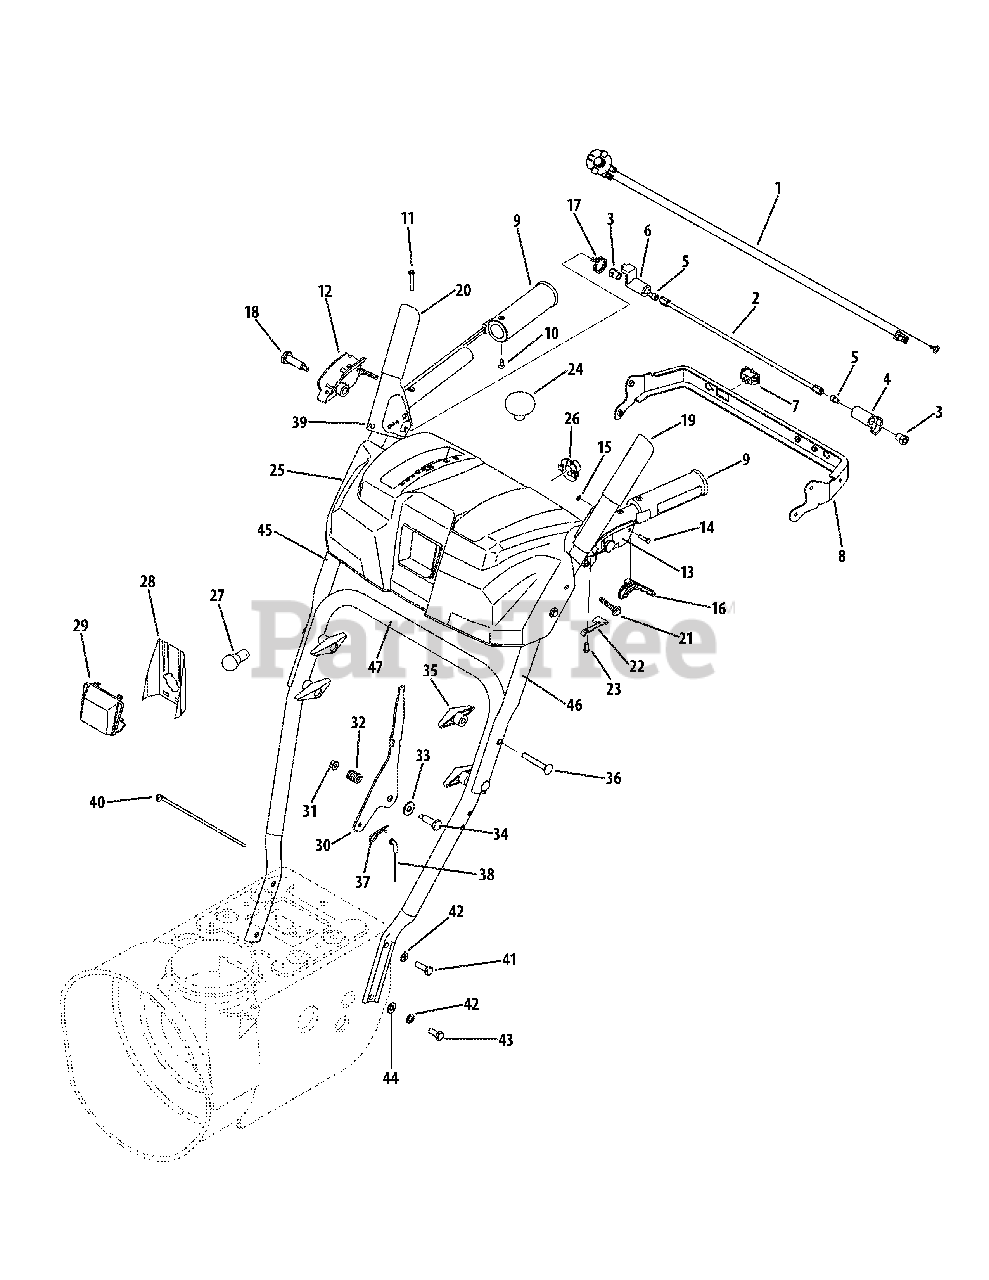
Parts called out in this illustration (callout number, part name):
1	Wire Harness
2	Clutch Lock Rod Assembly
3	Hex Shoulder Nut, 1/4-20
4	Clutch Lock Cam
5	Socket Cap Screw 1/4-20 x .50
7	Heated Grip Switch
8	Panel Bracket
9	Heated Grip
10	AB Screw, #10-16 x .625
11	Machine Screw, #10-24 x 1.375
12	Clutch Lock Handle Assembly, RH
13	Clutch Lock Handle Assembly, LH
15	E-Type Ring, .375
16	Clutch Trigger Lock
17	Torsion Spring, .8156 ID x .3038
18	Shoulder Screw, .437 x 1.345 x 1/4-20
19	Engagement Handle Assembly, LH
20	Engagement Handle Assembly, RH
21	Hex Washer Screw, 1/4-20 x 1.625
22	Clutch Lock Spring
23	Hex Washer Screw, #8-16 x .50
24	Shift Knob
25	Handle Panel
26	Light Socket
27	Lamp
28	Lens Label
31	Flange Lock Nut, 1/4-20
32	Compression Spring, .39 x .60 x .88
33	Flat Washer, .385 x .87 x .06
34	Shoulder Screw, .374 x 1.05
35	Knob Assembly, 5/16-18
36	Carriage Screw, 5/16-18 x 2.25
37	Click Pin, .092 x 1.64
38	Speed Selector Cable
39	Rubber Bumper, .62 x .22
40	Cable Tie, 3/16 x .05 x 7.43
41	Hex Bolt, 5/16-18 x 1.00
42	Lock Washer, 5/16
43	Hex Bolt, 5/16-18 x .75
44	Flat Washer, .344 x .688 x .065
45	Upper Handle, RH
46	Upper Handle, LH
